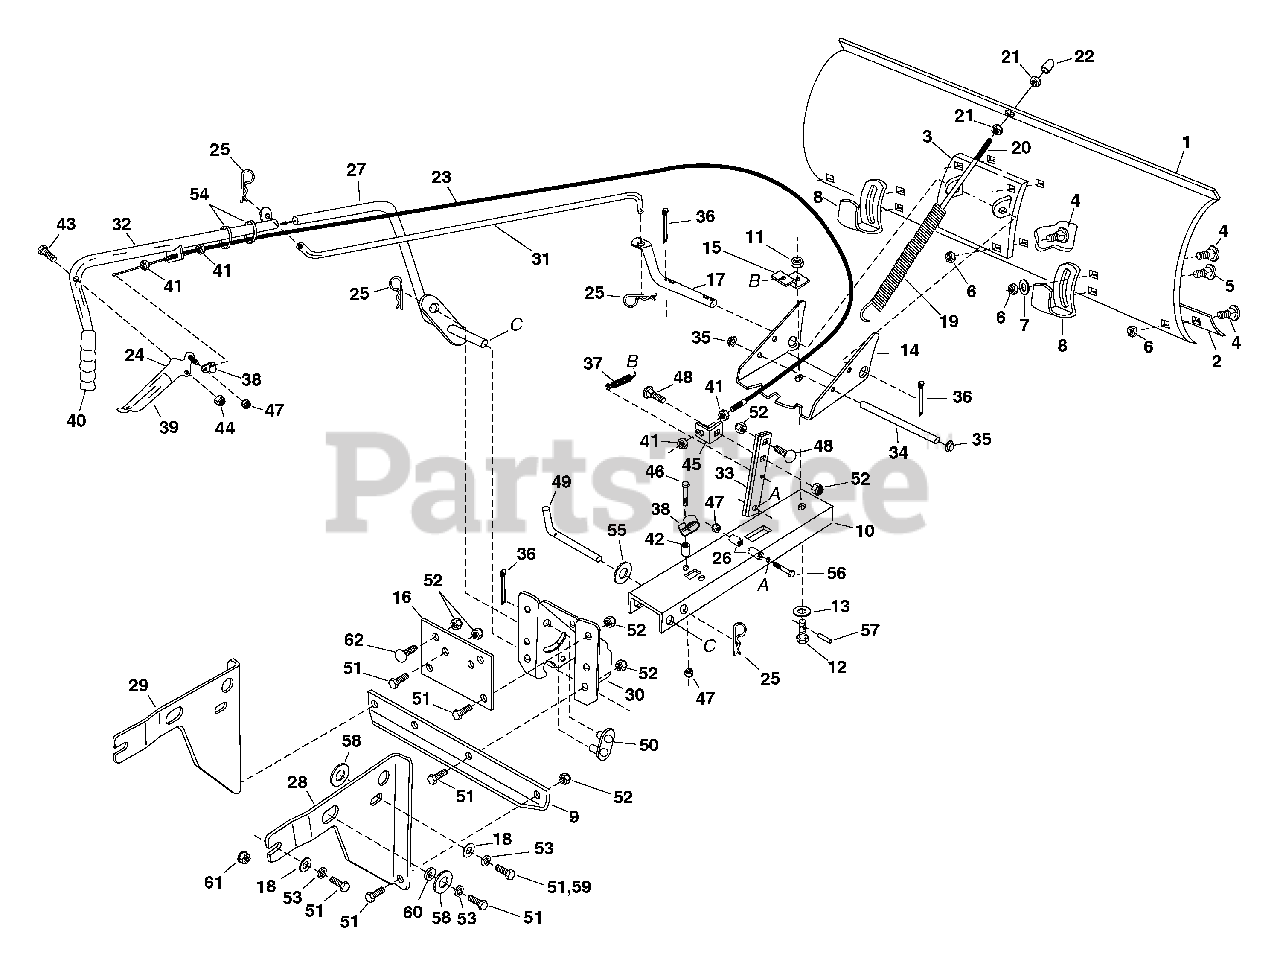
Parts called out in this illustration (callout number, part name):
1	Blade 48"
2	Wear Plate 48"
3	Reinforcement Plate Assembly
4	Bolt, Carriage 5/16-18 x 3/4"
5	Bolt, Carriage 5/16-18 x 1"
6	Hex Lock Nut, 5/16-18 Thread
7	Washer, 5/16"
8	Skid Shoe
9	Bracket, Cross Tie
10	Push Channel
11	Hex Lock Nut, 1/2-13 Thread
12	Bolt, Special Pivot
13	Washer, Flat 1/2"
14	Plate, Pivot 7 Ga.
15	Bracket, Spring Mt.
16	Bracket, Pivot Plate
17	Shaft, Blade Pivot
18	Washer, 3/8" STD.
19	Spring, Blade Adjust
20	Hex Bolt, 3/8-16 x 3-1/2"
21	Hex Nut, 3/8-16 Thread
22	Plastic Cap
23	Control Cable Assembly
24	Release Grip Assembly
25	Pin, Hairpin Small 3/32"
26	Spacer,
27	Lift Handle Rod Assembly
28	Hanger Bracket, R.H.
29	Hanger Bracket, L.H.
30	Pivot Support Bracket
31	Rod, Blade Pivot
32	Lift Handle Tube Assembly
33	Angle Lock Bar
35	Palnut,
36	Cotter Pin 1/8" x 1-1/4"
37	Angle Lock Spring
38	Cable End Fitting
39	Grip, Plastic
40	Handle, Grip
41	Hex Jam Nut, 5/16-24 Thread
43	Hex Bolt, 5/16-18 x 1-1/2"
44	Hex Nut, Nylock 5/16-18 Thread
45	Cable Mount Bracket
46	Hex Bolt 1/4-20 x 1-1/2"
47	Hex Nut, Nylock 1/4-20 Thread
48	Carriage Bolt, 3/8-16 x 1-1/4"
49	Channel Pivot Pin
50	Lift Link Assembly
51	Hex Bolt, 3/8-16 x 1"
52	Hex Nut, Nylock 3/8-16 Thread
53	Lock Washer 3/8"
54	Plastic Tie
56	Hex Bolt, 1/4-20 x 3-1/4" Lg. Gr 5
57	1/4" x 1" Spring Pin
58	Washer, 1/2" (Large)
59	Hex Bolt, 3/8" x 1" (Thd. Forming)
61	Flanged Nut, 5/16-18 (Whizlock)
62	Carraige Bolt, 3/8-16 x 1"
